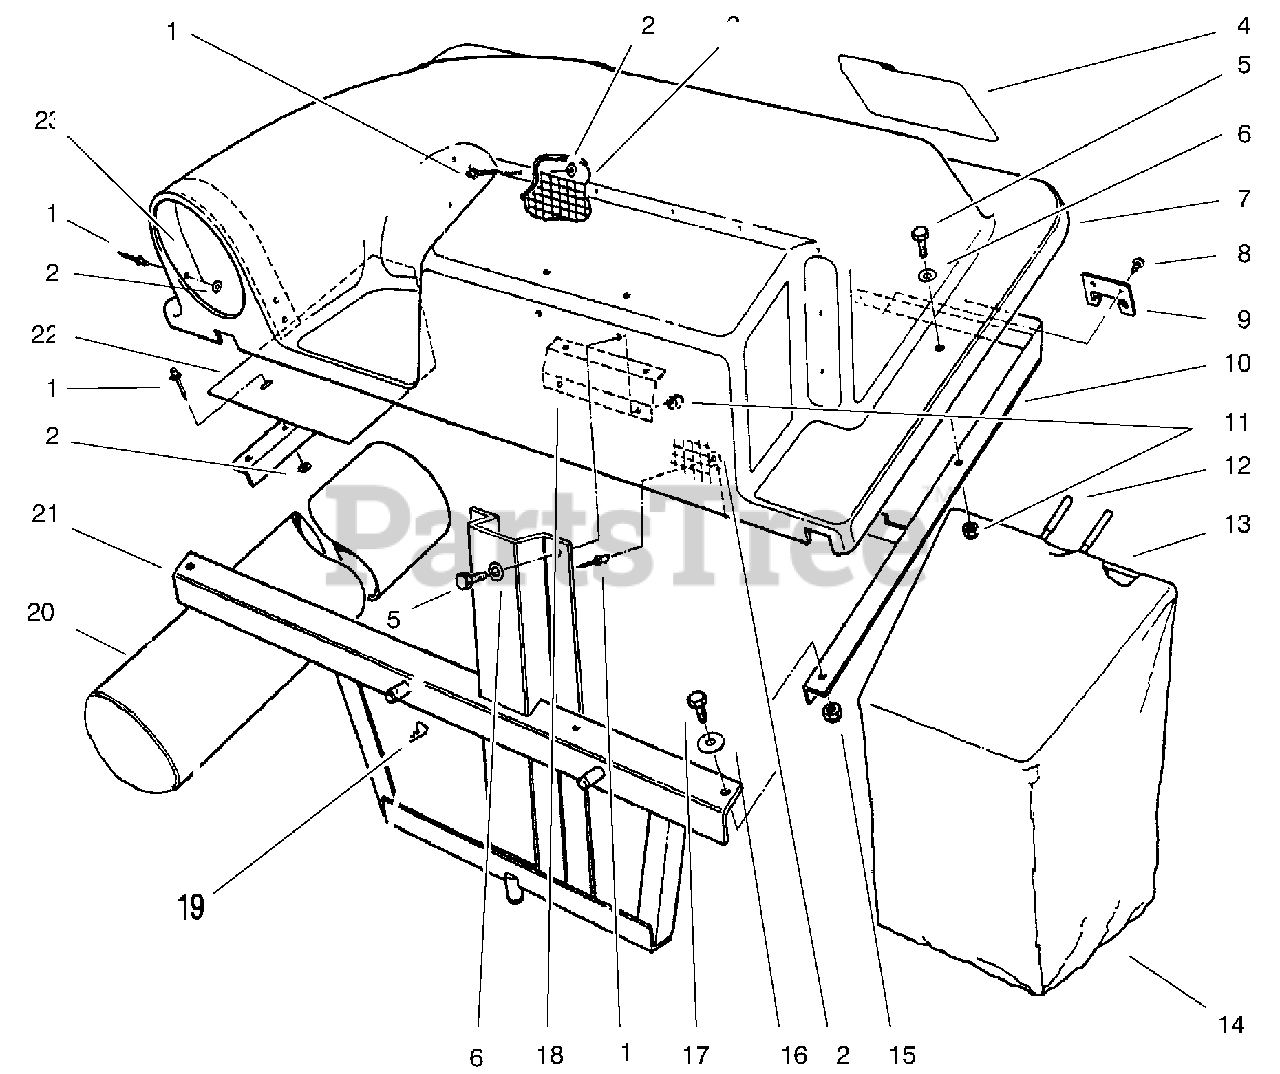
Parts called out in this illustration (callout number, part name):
1	RIVET-POP
2	WASHER-FLAT
4	DECAL-TWIN BAGGER
5	SCREW-HH
6	WASHER-FLAT
7	TWIN BAGGER COVER
8	SCREW-HWH
9	BAG FRAME BRKT
10	Cover-Frame
11	NUT-LOCK, NI
12	GRIP-HANDLE, BAG
13	BAG FRAME (BLACK)
15	NUT-LOCK, NI
16	WASHER-FLAT
17	SCREW-HH
18	Plate-Backup
20	DUCT - BAGGER
21	Frame-Mounting
22	Baffle
23	Support Inlet
